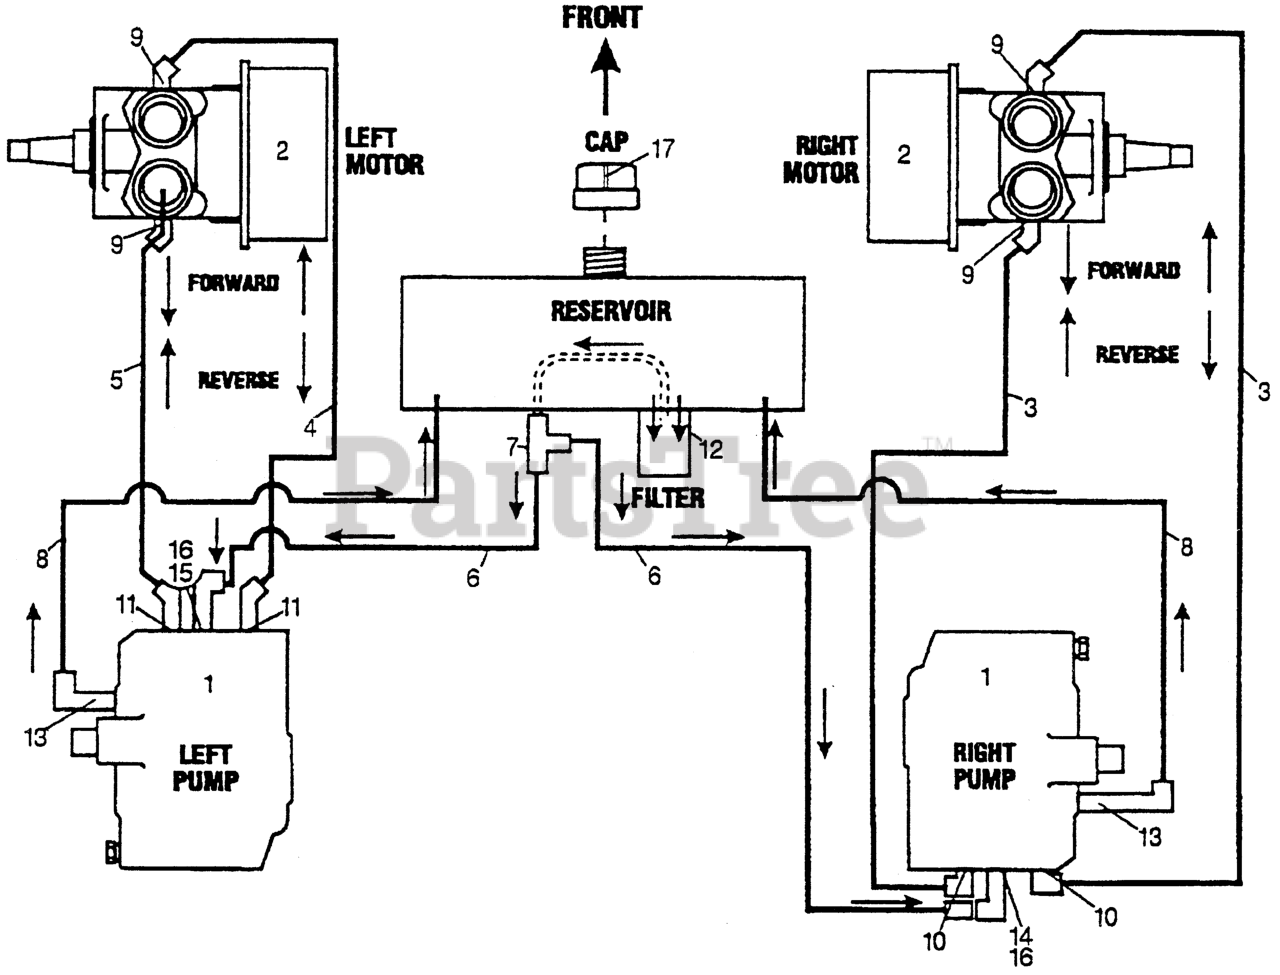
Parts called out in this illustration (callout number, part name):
1	PUMP ASSY., HYDRAULIC (SEE KIT 25010-VE4-000--END OF BLOCK)
2	MOTOR ASSY., HYDRAULIC
3	HOSE ASSY., R. MOTOR
4	HOSE ASSY. A, L. MOTOR
5	HOSE ASSY. B, L. MOTOR
6	HOSE ASSY., PUMP
7	ADAPTER, TANK SUPPLY HOSE
8	HOSE ASSY., PUMP RETURN
9	ADAPTERM MOTOR-HOSE
10	ADAPTER, R. PUMP MOTOR
11	ADAPTER, L. PUMP MOTOR
12	FILTER, HYDRAULIC
13	ADAPTER, PUMP CASE
14	ADAPTER, R. PUMP CHARGE
15	ADAPTER, L. PUMP CHARGE
16	ADAPTER, PUMP CHARGE HOSE
17	CAP ASSY., RESERVOIR
NI	SEAL KIT, PUMP
NI	SEAL SET, MOTOR (WHITE)
